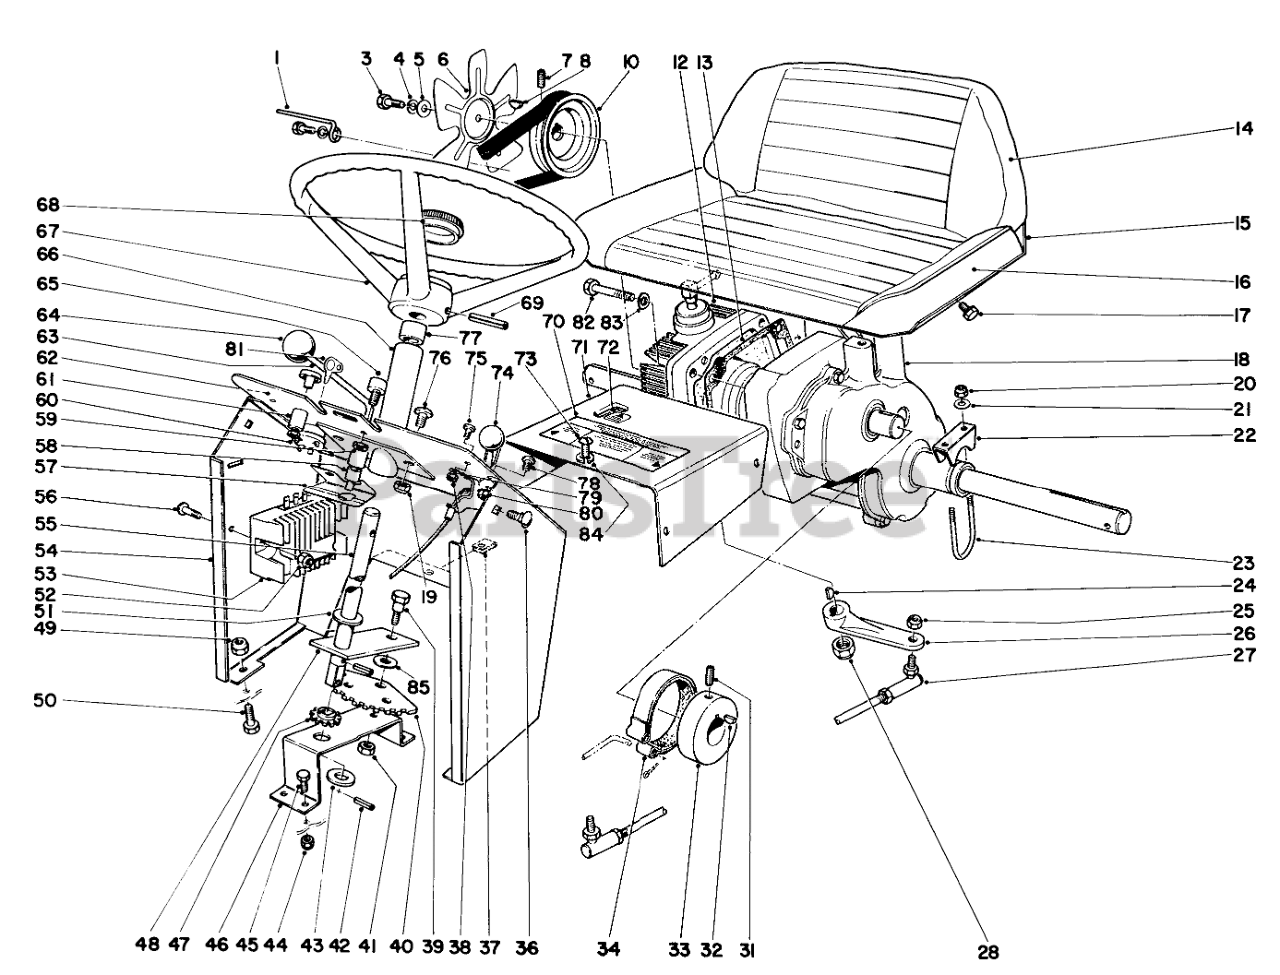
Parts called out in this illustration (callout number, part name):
1	Belt Guide
3	SCREW-HH
4	WASHER-LOCK
5	WASHER-FLAT
7	SCREW-SET, HSH
8	KEY-WOODRUFF
10	Pulley
12	Hydrostatic Transmission
13	Gasket
14	Cushion Back
15	Frame Seat
16	Cushion Seat
17	Screw
18	Transaxle
19	Nut
20	Locknut
21	WASHER-FLAT
22	Axle Bracket
23	U-Bolt
24	KEY-WOODRUFF
25	Locknut
26	Lever Hydrostatic
27	Control Rod Transmission
31	SCREW-SET
32	KEY-WOODRUFF
33	Brake Drum
34	Brake Band
36	BOLT-CARR
37	SPEED NUT
38	NUT-HEX
39	Shoulder Bolt
40	Gear Steering
41	Nut
42	PIN-ROLL
43	WASHER
44	Nut
45	SCREW-HH
46	Bracket
47	STEERING PINION
48	Retainer Steering Gear
49	Nut
50	SCREW-HH
51	WASHER
53	Regulator, Rectifier
54	Dash Hood Support
55	Steering Shaft
56	Screw, Phillips
57	Spring Detent
58	Bushing
60	Switch
61	Light Switch
62	Decal Dash
63	Handle Hydro Control
66	Steering Tube Incl. Ref. #77
67	Steering Wheel
68	Steering Wheel Cap
69	Roll Pin
70	Decal
71	Tunnel
72	Decal Push Engage
73	SCREW
74	Throttle Control
76	Truss Head Screw
77	Bushing
78	Machine Screw
79	WASHER-LOCK, EXT
80	NUT-KEPS
81	Key
82	SCREW-HH
83	WASHER-LOCK
84	WASHER-LOCK
85	WASHER
